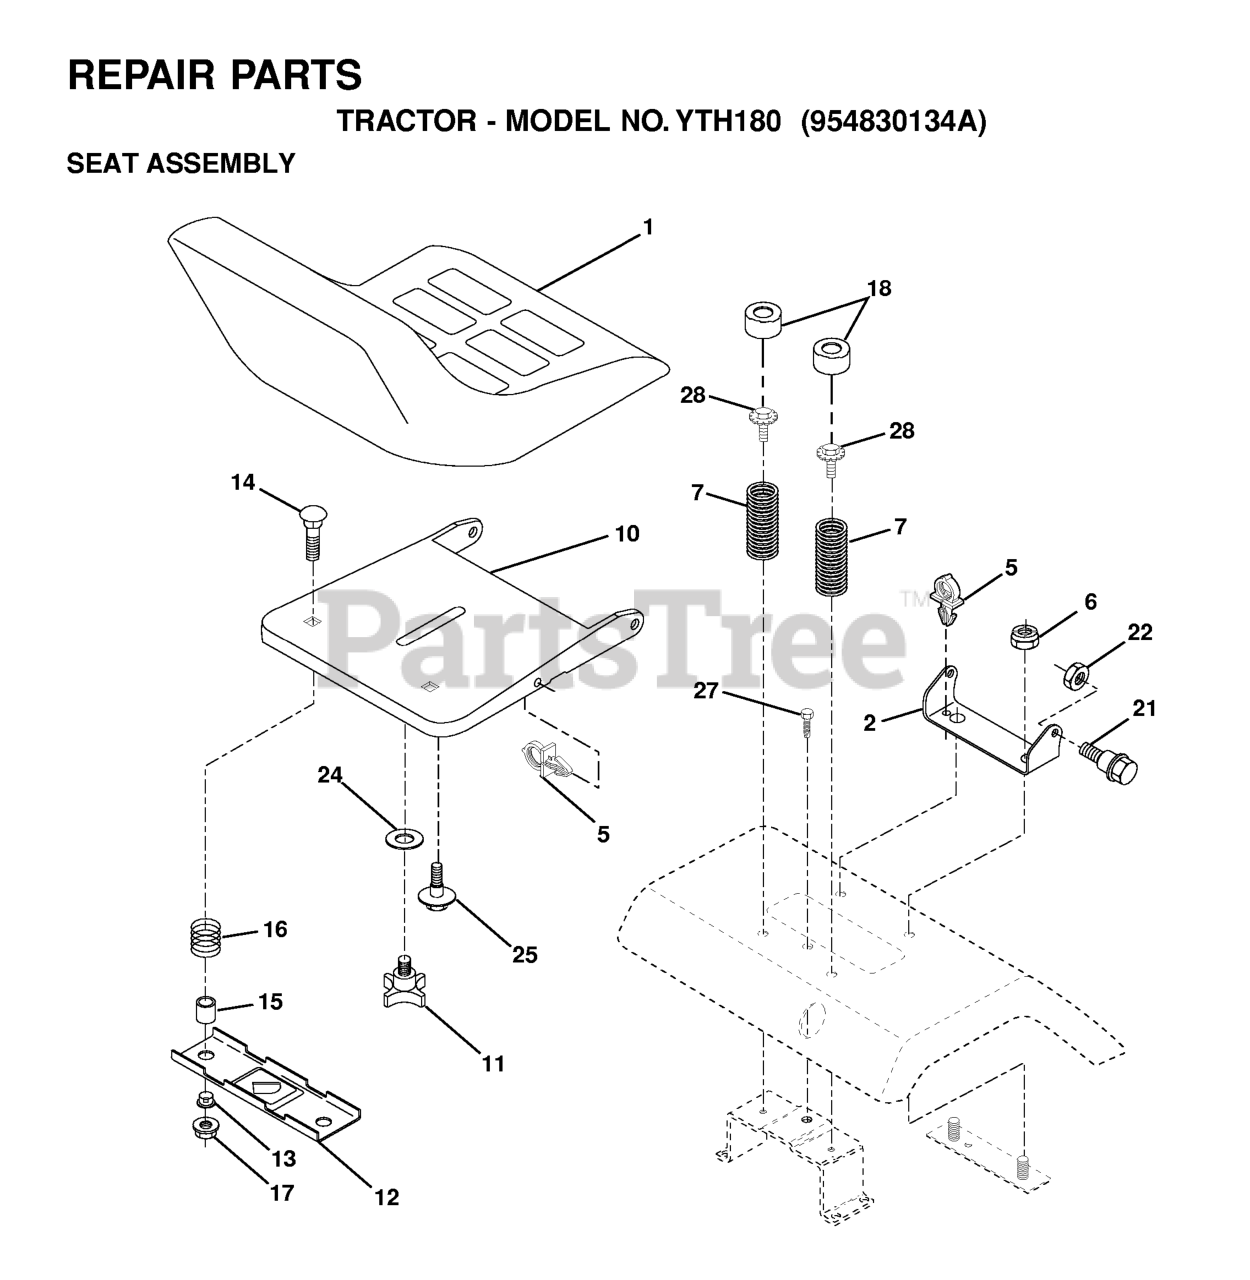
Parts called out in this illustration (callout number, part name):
1	SEAT, GRAY
2	SEAT PIVOT BRKT
6	NUT
7	SPRING COMPRESSION
10	SEAT PAN
11	KNOB 1/2" YT
12	BRKT SWITCH
14	Bolt Rdhd. Sht. Nk 1/4-20 x 1-3/8
15	SPACER SPLIT
16	SPRING COMPRESSED
17	NUT T
18	CAP SPRING
21	BOLT.SHOULDER.5/16-18
22	LOCKNUT
25	BOLT,SHOULD
28	BOLT HEX WASHER HD 5/16-18
